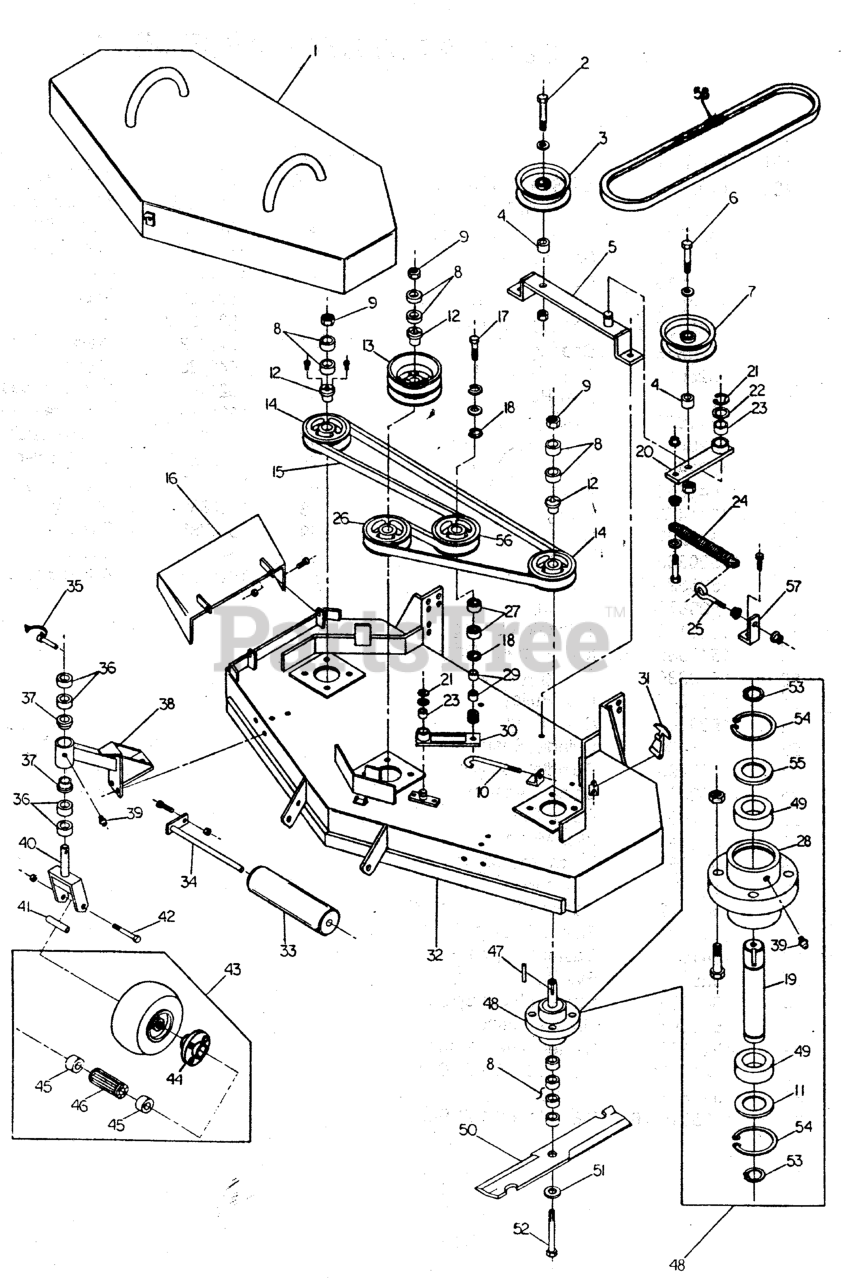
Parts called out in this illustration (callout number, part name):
1	61" DECK GUARD
2	BOLT, 1/2-13 X 3-1/2, HEX HD, GD5, CZ (SV)
3	PULLEY, Backside Idler
4	SPACER, .50 x 1.00 X .69
5	Idler Mount
6	BOLT, 1/2-13 X 3" GD5 CZ
7	PULLEY, V-Idler
8	SPACER, .63 x 1.06 x .23
9	NUT, 5/8-11 Hex
11	SPINDLE WASHER, Bottom
12	BUSHING, Tapered Hub
13	Double Pulley
13	PULLEY, Spindle
13	PULLEY, Split Steel
14	PULLEY, Spindle
14	PULLEY, Split Steel
15	BELT, Blade Spindle
15	Deck Drive Belt
16	CHUTE, DISCHARGE WELDMENT
17	BOLT, 1/2-20 x 2-1/4
18	SNAP RING, Internal
19	SPINDLE SHAFT
20	IDLER ARM, Complete
21	C-CLIP
22	SHIM
23	BUSHING, Brass
24	SPRING, Extension
25	EYEBOLT
26	SPINDLE PULLEY
26	PULLEY, Split Steel
27	BEARING, BALL 11/16X1-9/16X15/32
28	SPINDLE HOUSING
29	INSERT, Bearing
30	IDLER ARM
31	RUBBER LATCH
32	61" MOWER HOUSING (4 Bolt)
33	ROLLER
35	PIN, Lynch
36	SPACER, 1.02 x 1.56 x .50
37	BUSHING, Flange
38	Caster Support
39	GREASE FITTING
40	YOKE, Caster
41	AXLE, Caster Wheel
42	BOLT, 1/2-13 x 5-1/2
43	Caster Assembly
43	WHEEL & TIRE ASSEMBLY, White, 9 x 3.5 x 4, Complete
43	TIRE ASSM, Solid Rubber, 9 X 3.5
45	RETAINER, Bearing
46	BEARING, ROLLER 3/4" ID X 3.25" (ONE PER TIRE)(SV)
47	KEY, 1/4 SQ. X 2-1/2
48	SPINDLE ASSEMBLY, Complete
49	BEARING
50	MOWER BLADE, 21"
51	WASHER, 5/8" SAE
52	BOLT, 5/8-11 x 9-1/2
53	SNAP RING, External
54	SNAP RING, Internal
55	SPINDLE WASHER, Top
56	PULLEY, Idler
56	PULLEY, Backside Idler
57	SPRING ANCHOR
58	BELT, B-Section
